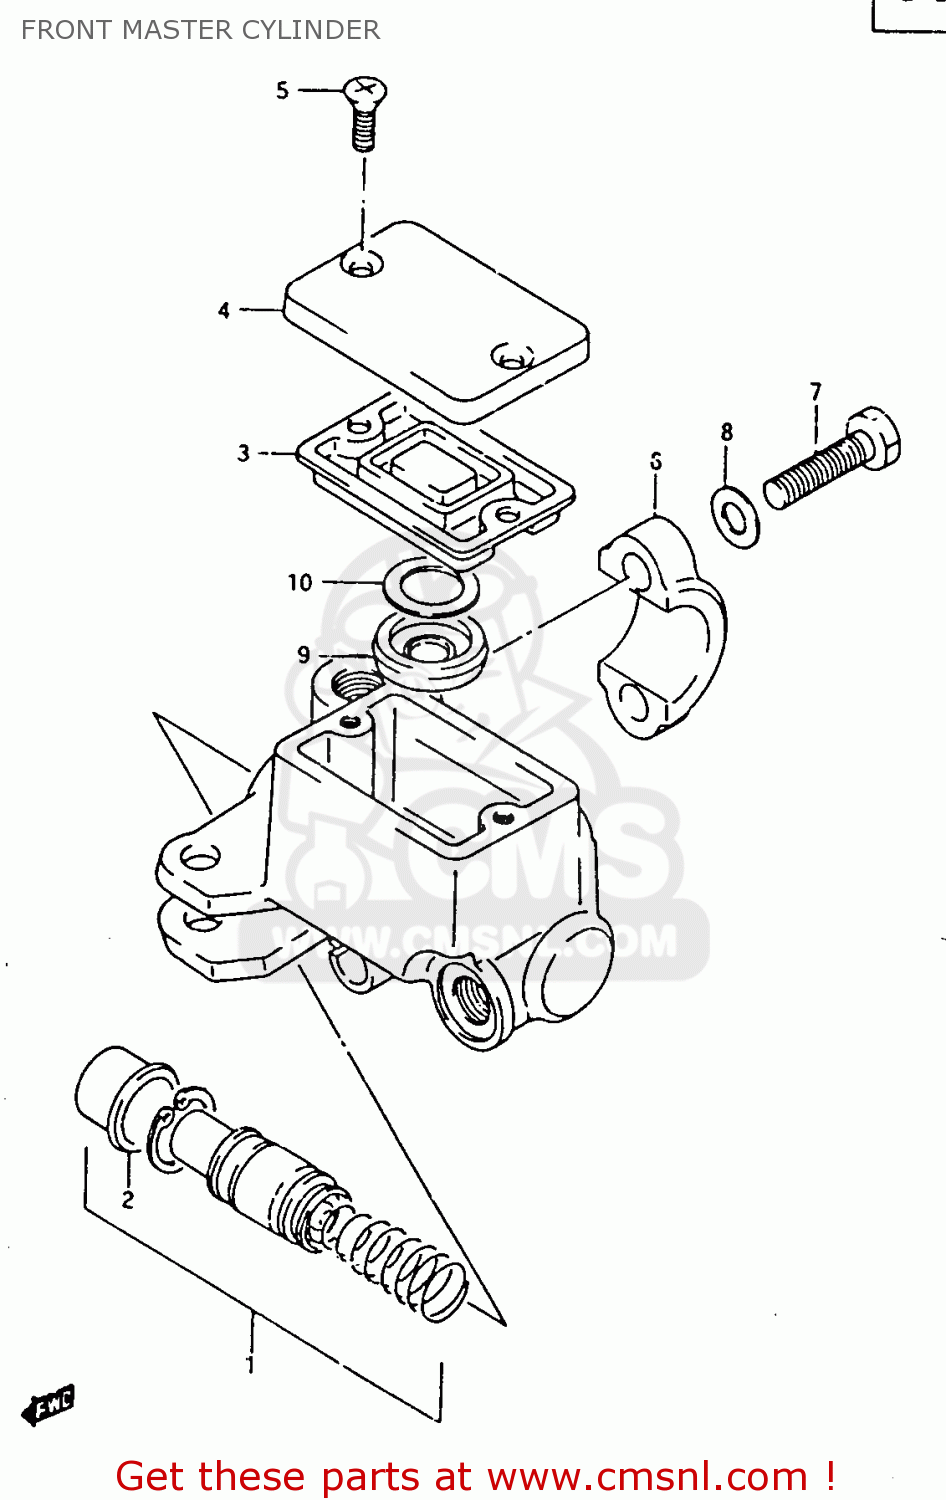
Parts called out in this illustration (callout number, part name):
1	PISTON & CUP SET
2	BOOT
3	DIAPHRAGM
4	CAP
5	SCREW
6	HOLDER
7	BOLT
8	WASHER
9	SEPERATOR
10	PLATE
